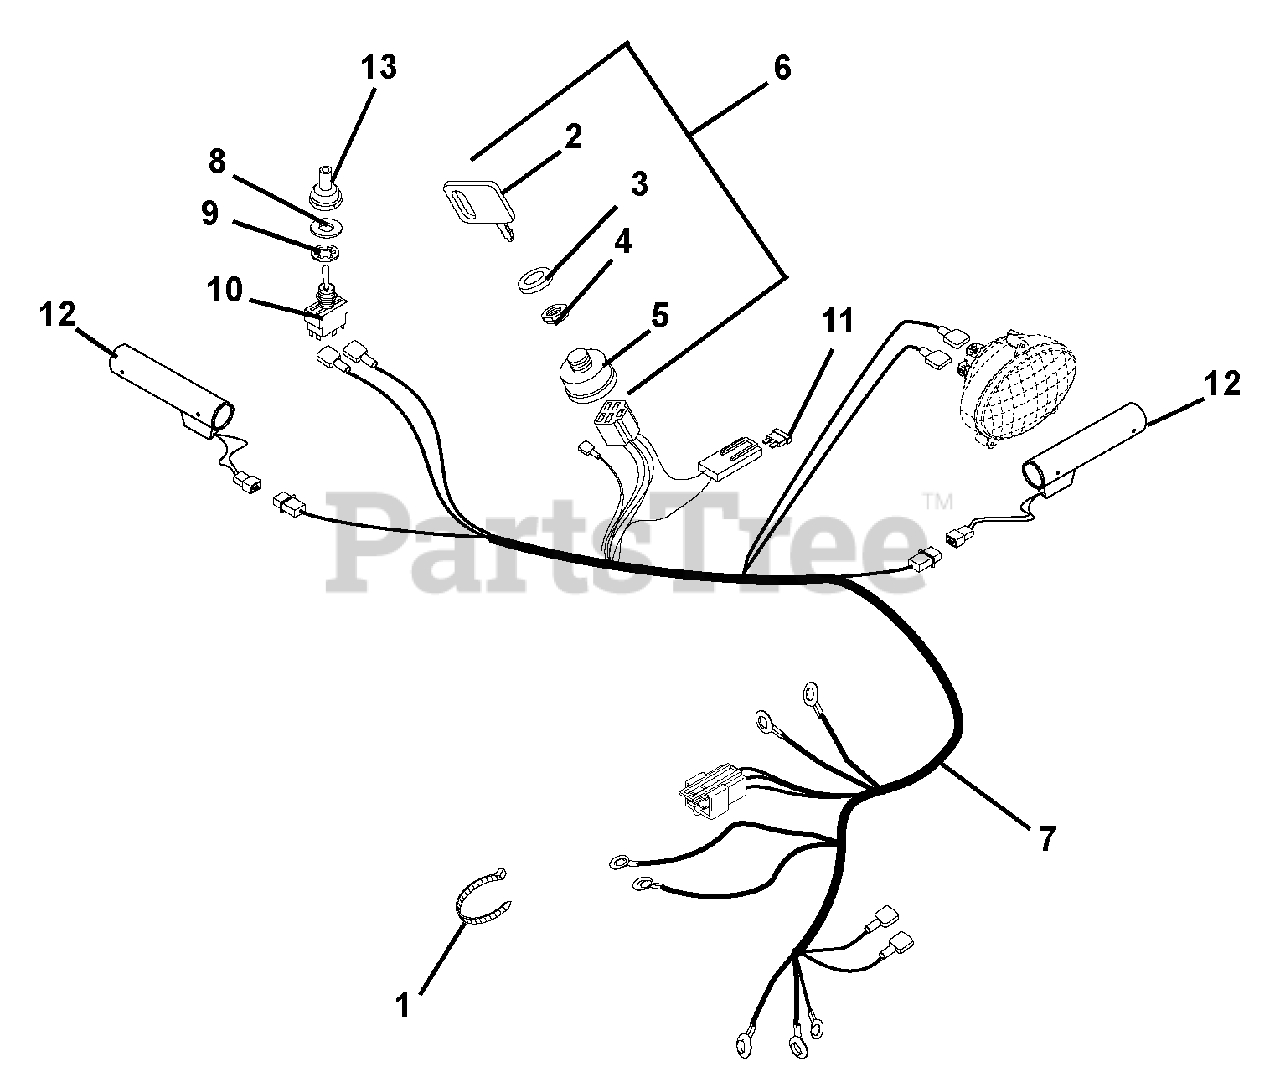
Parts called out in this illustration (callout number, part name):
1	CABLE TIE LG 5-1/2
2	KEY -W/CAP
3	CAP - IGNITION SWITCH
4	NUT-PANEL .625-32 GRECO
5	IGNITION SWITCH ASSEMBLY
6	SWITCH ASSEMBLY
7	HARNESS, WIRE-LIGHT HANDWARMER
7	HARNESS, WIRE-LT, HW, 12V
8	WSHR-FL-STL .505X.875X.024 PL
9	WSHR-LK-INT .563X.040 YWZC
10	SWITCH, ON/OFF
11	FUSE, 15 AMP.
12	WARMER, HAND W/TERMINAL
13	BOOT, SWITCH
